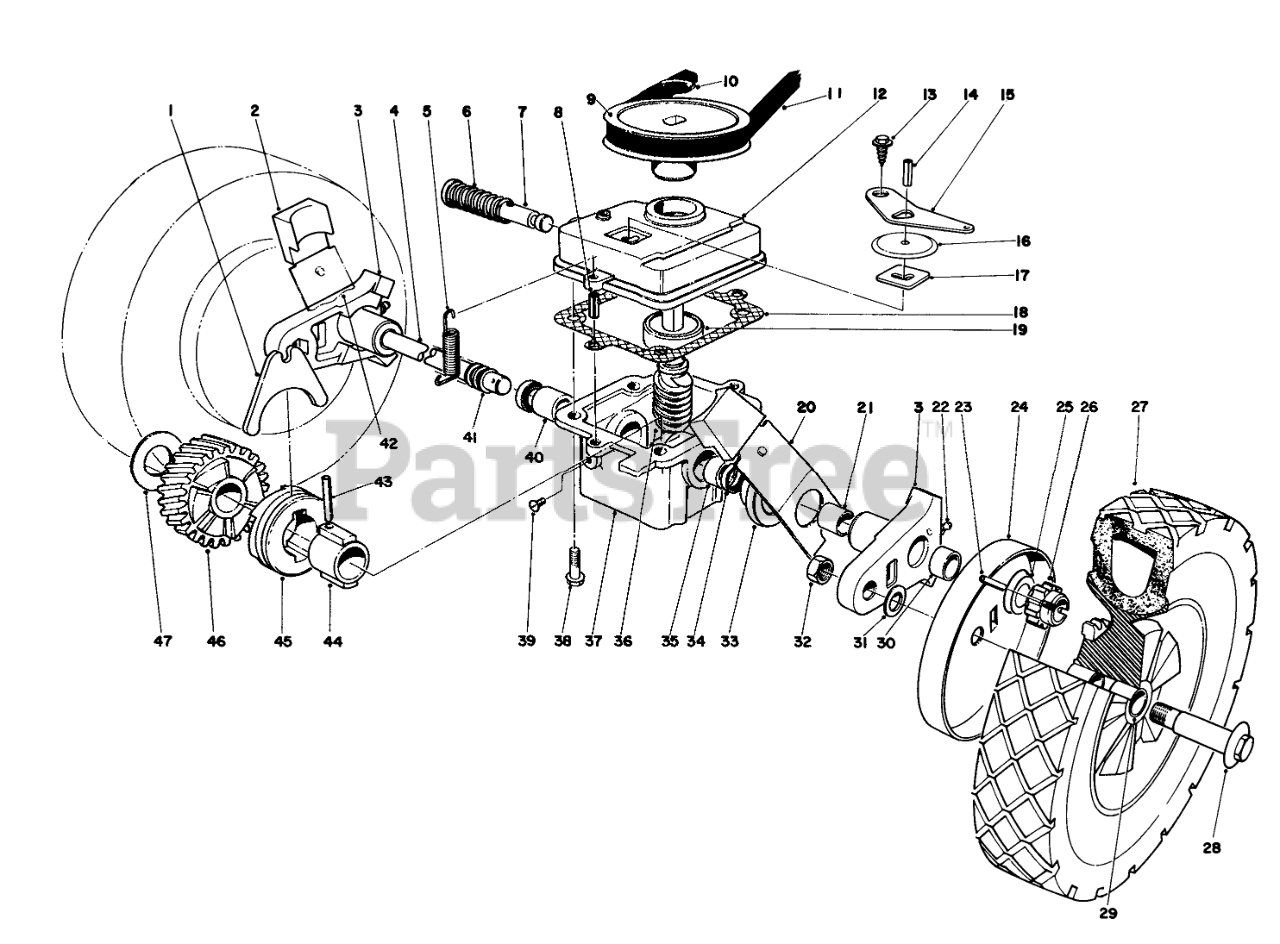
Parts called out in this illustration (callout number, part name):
1	SHIFTER FORK
2	KNOB-ARM
3	Pivot Arm (Incl. Ref. #21, 22 & 30)
4	DRIVE SHAFT (SERVCE)
5	TENSION SPRING
6	SPRING
7	Shift Rod
8	3/16 X 1/2 ROLL PIN
9	PULLEY
10	PUSH-ON 93-3236
11	V BELT
12	Case-Upper
13	Screw
14	PIN-ROLL
15	SHIFTER ARM
16	TRANS DUST COVER
17	LATCH PLATE
18	GASKET
19	Bearing
20	SPRING ARM ASM SP LH
21	BUSHING
22	FITTING-GREASE
23	Pin
24	WHEEL COVER
25	WASHER-THRUST
26	Pinion
27	Wheel & Tire Assembly (Incl. Ref. #29)
28	BOLT-WHEEL
29	BUSHING
30	BUSHING
31	WASHER
32	Nut
33	End Cap
34	Seal
35	Bushing
36	Worm Shaft & Gear (Incl. Ref. #46) (used on units with serial no. 2006878 & up)
37	Gear Case (Incl. Ref. #34, 35 & 40)
38	Screw
39	NYLON SCREW
40	Bushing
41	COVER-SHAFT, DRIVE
42	SPRING ARM ASM SP RH
43	COIL PIN
44	SLEEVE
45	CLUTCH JAW
46	Helical Gear
47	THRUST WASHER
